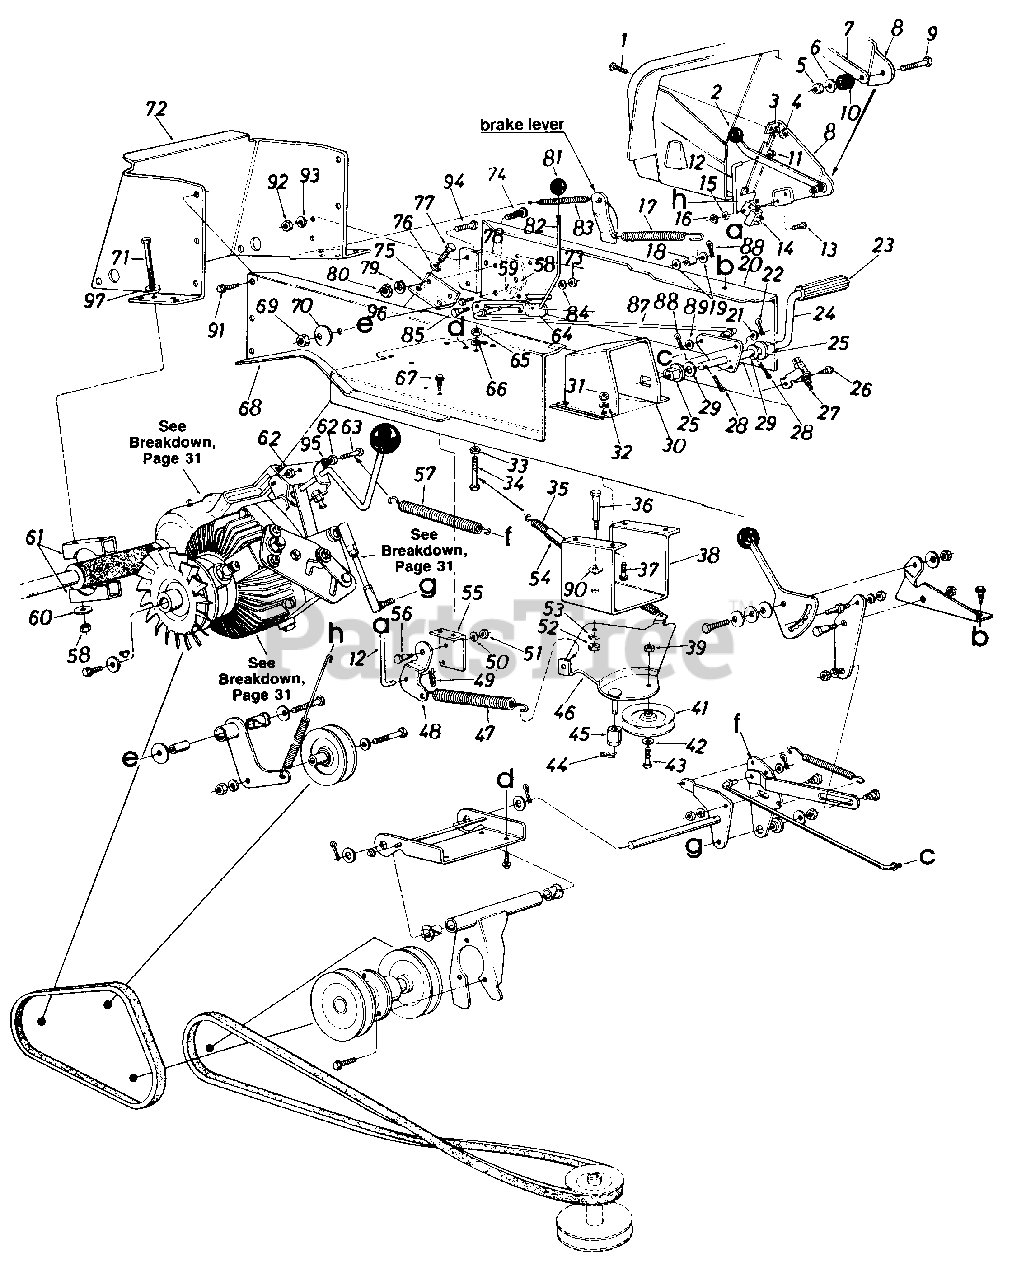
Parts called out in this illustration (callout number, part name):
1	Truss Mach. Scr. 1/4-20 x .50" Lg.
2	"T" Knob Blade Clutch
4	Hex Sems Nut 1/4-20 Thd.
5	Hex Cent. L-Nut 1/4-20 Thd.
6	Fl-Wash. 1/4" I.D. x .75" O.D.
7	PTO Lever
8	Deck Clutch Control Brkt.
9	Hex Bolt 1/4-20 x .75" Lg.
10	Rubber Wash. .33" I.D. x .87" O.D.
11	Push Cap 1/4" Rod
12	Deck Control Rod
13	Truss Mach. Scr. #10-24 x .50" Lg.
14	Safety Switch
15	Ext. L-Wash. #10 Scr.
16	Hex Nut #10-24 Thd.
17	Extension Spring .75" O.D. x 5.56" Lg.
18	Spacer .375" I.D. x .625" O.D. x .445" Lg.
19	Fl-Wash. .385" I.D. x .87" O.D.
20	Side Panel Upper Frame L.H.
21	Fl-Wash. .385" I.D. x .87" O.D.
22	Cotter Pin 3132" Dia. x .75"
23	Foot Pad
24	Foot Pedal Brkt. Ass'y.
25	Flange Brg. .630" I.D. x 1.25" O.D.
26	Hex Wash. Hd. S-Tap Scr. 1/4-20 x .50" Lg.
27	Safety Switch
28	Cotter Pin 1/8" Dia. x 1.00"
29	Fl-Wash. .640" I.D. x .24" O.D.
30	Steering Gear Support Ass'y.
31	Fl-Wash. .385" I.D. x .87" O.D.
32	L-Wash. 5/16" I.D.
33	Hex Nut 1/4-20 Thd.
34	Hex Bolt 1/4-20 x 2.0" Lg.
35	Extension Spring .50" O.D. x 6.37" Lg.
36	Shld. Bolt 7/16" Dia. x .16"
37	Hex Bolt 5/16-18 x 1.00"
38	Idler Mtg. Brkt. Deck
39	Hex L-Nut 3/8-16 Thd.
41	"V"-Idler Pulley
42	Fl-Wash. 3/8" I.D.
43	Hex Bolt 3/8-16 x 1.75" Lg.
44	Cotter Pin 5/16" Rod
45	Spacer
46	Idler Brkt. Ass'y.
47	Extension Spring Deck Control
48	Deck Control Pivot Brkt.
49	Cotter Pin 5/16" Rod
50	L-Wash. 5/16" I.D.
51	Hex Nut 5/16-18 Thd.
52	Hex Nut 5/16-18 Thd.
53	L-Wash. 5/16" I.D.
54	Convoluted Conduit .50" I.D. x 4" Lg.
55	Parking Brake Cam Mtg. Brkt.
56	Shld. Bolt 7/16" Dia. x .16"
57	Extension Spring
58	Hex Nut 3/8-16 Thd.
59	L-Wash. 3/8" I.D.
60	Bell-Wash .39" I.D. x 1.13"
61	Rear Axle Brkt.
62	Hex Nut 5/16-24 Thd.
63	Hex
64	Parking Brake Cam
65	Hex Nut 1/4-20 Thd.
66	L-Wash. 1/4" I.D.
67	Hex Wash. Hd. S-Tap Scr. 1/4-20 x .50" Lg.
68	Side Panel Upper Frame R.H.
69	Hex Nut 3/8-24 Thd.
70	Fl-Wash. .39" I.D. x 1.5" O.D.
71	Hex Bolt 3/8-16 x 3.50" Lg.
72	Hitch Plate
73	Hex Nut 3/8-16 Thd.
74	Rd. Hd. Ribbed Neck Bolt 3/8-24 x 1.0" Lg.
75	Mounting Brkt. Transaxle
76	L-Wash. 3/8" I.D.
77	Hex Bolt 3/8-16 x 1.00" Lg. (Grade S)
78	Reinforcement Plate Frame
79	L-Wash. 3/8" I.D.
80	Hex Nut 3/8-24 Thd.
81	"T" Gear Shift Knob
82	Parking Brake Link
83	Extension Spring .38" O.D. x 3.18" Lg.
84	Hex Nut 3/8-16 Thd.
85	Shld. Bolt .500" Dia. x .170
87	Rod Brake .38" Dia. x 19.3" Lg.
88	Cotter Pin 3132" Dia. x .75"
89	Fl-Wash. .385" I.D. x .87"
90	Wave Wash.
91	Hex AB-Tap Scr. 5/16 x .75"
92	Hex Nut 5/16-24 Thd.
93	L-Wash. 5/16" I.D.
94	Hex Bolt 5/16-24 x .75" Lg.
95	L-Wash. 5/16" I.D.
96	Hex Bolt 3/8-16 x .75" Lg.
97	Fl-Wash. .385" I.D. x .870" O.D.
